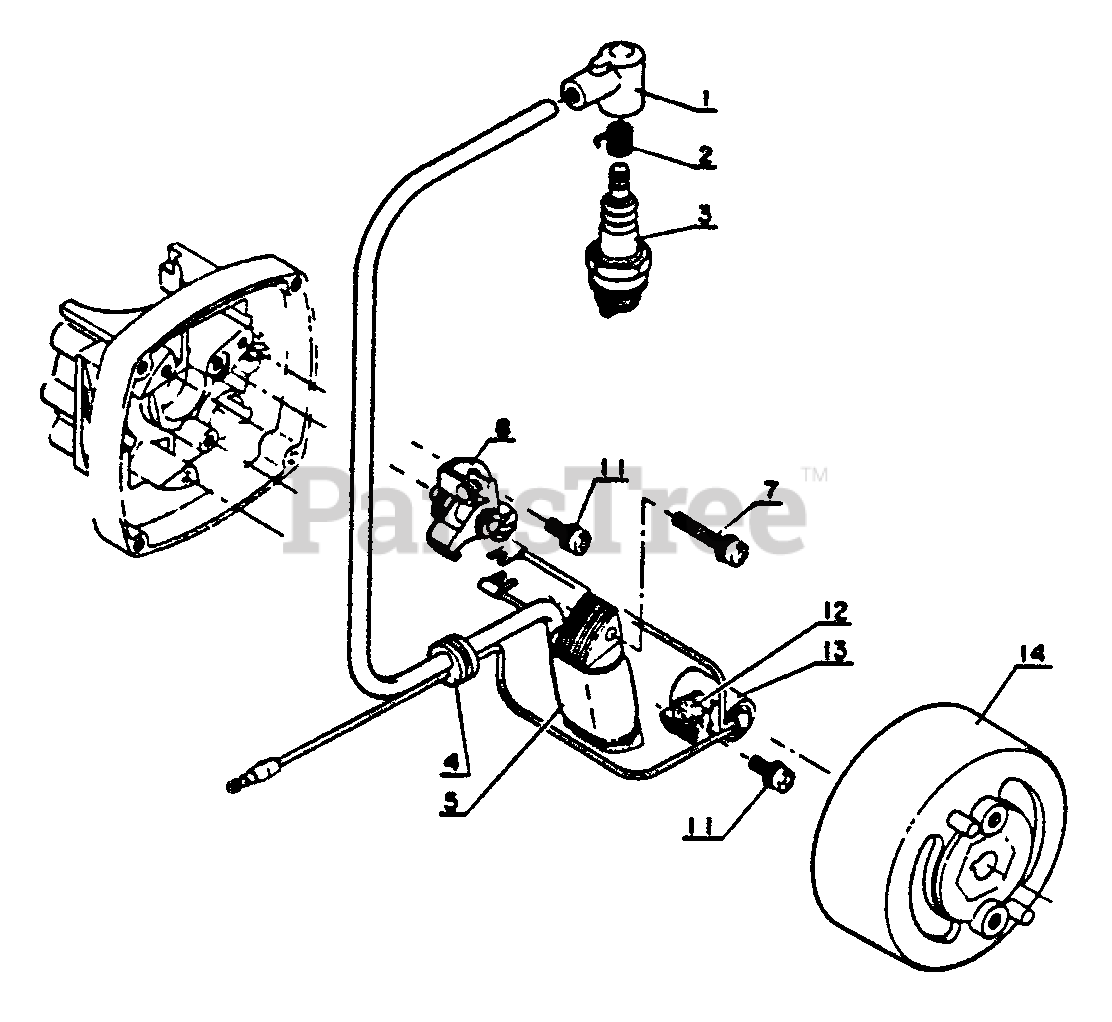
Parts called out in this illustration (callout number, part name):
1	CAP, SPARK PLUG
2	TERMINAL, SPARK PLUG CAP
3	SPARK PLUG - BM6A
5	COIL, IGNITION
7	SCREW 4×25
8	CONTACT POINT SET
11	SCREW 4×10
12	PAD, OIL
13	CONDENSER
14	FLYWHEEL
